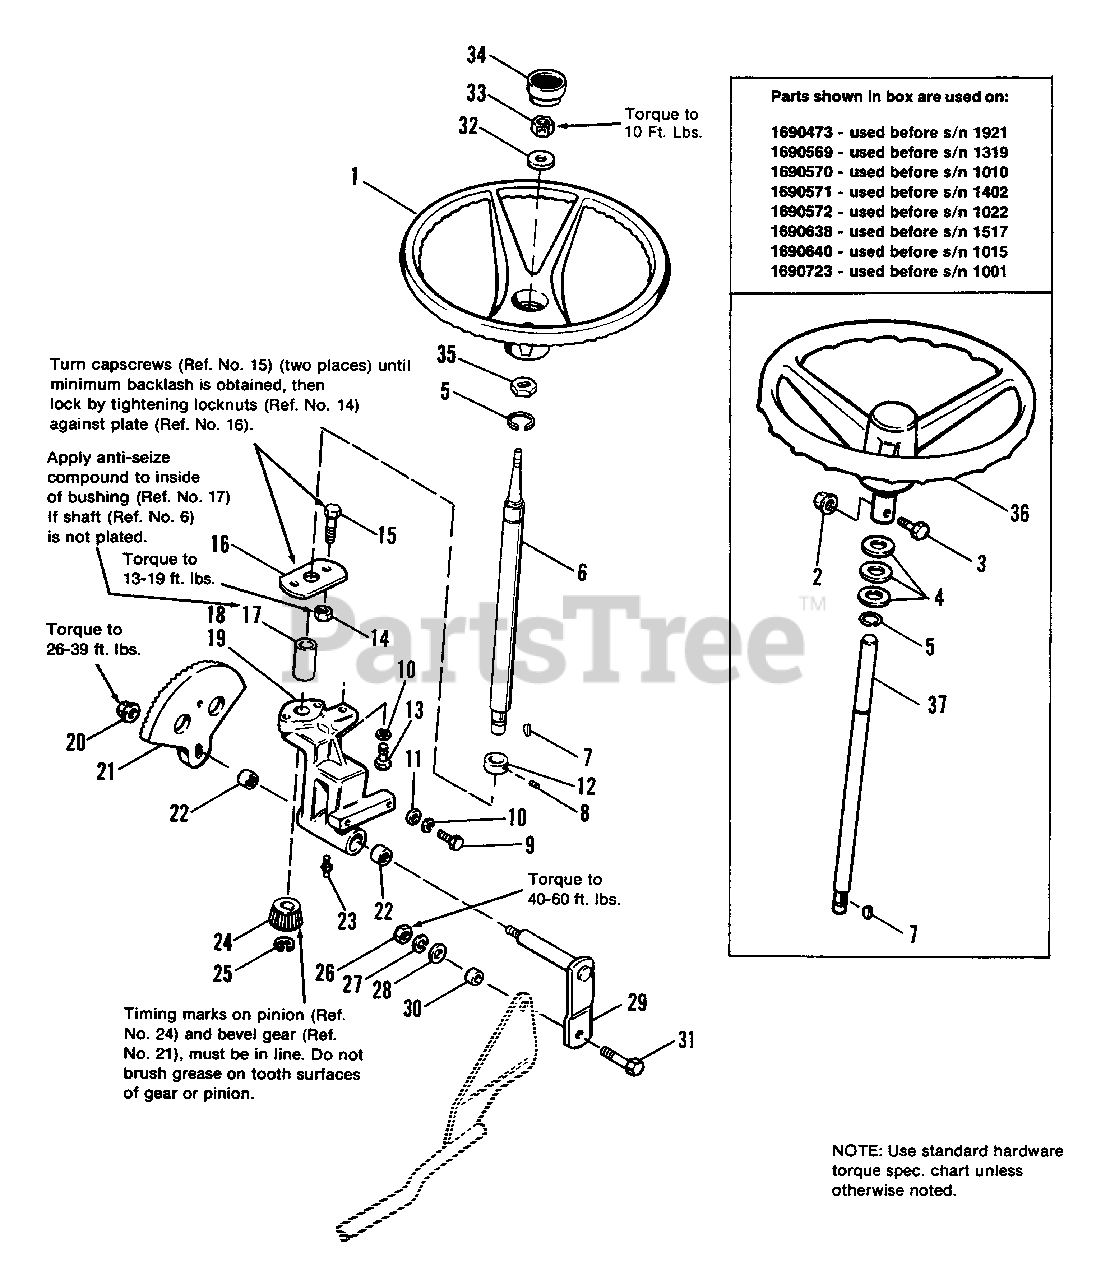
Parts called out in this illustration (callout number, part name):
1	WHEEL, Steering
2	LOCKNUT, Hex, Flange, 5/16-18
3	CAPSCREW, Hex Hd., 5/16-18 x 1-1/4
5	RING, Retaining
6	SHAFT, Steering
7	KEY, Woodruff, #6
8	SETSCREW, 5/16-18 x 1/4
9	CAPSCREW, Hex Hd., 3/8-16 x 7/8
10	LOCKWASHER, 3/8
11	WASHER, Plain, 3/8
12	COLLAR, Set
13	CAPSCREW, Hex Hd., 3/8-16 x 3/4
14	LOCKNUT, Hex, Jam, 3/8-16
15	CAPSCREW, Hex Hd., 3/8-16 x 1-1/4
16	PLATE, Steering
18	HOUSING ASSY., Steering (Incl. Ref. Nos. 17 & 22)
19	HOUSING, Steering
20	LOCKNUT, Hex, Flange, 7/16-14
21	GEAR, Bevel
22	BEARING, Needle
23	FITTING, Grease
24	PINION, Bevel
25	E-RING
26	NUT, Hex, Full, 1/2-13
27	LOCKWASHER, 1/2
28	WASHER, Plain, 1/2
29	ARM ASSY., Steering
31	CAPSCREW, Hex Hd., 1/2-13 x 1-1/2
32	WASHER, Compression
33	LOCKNUT, Hex, Cntr. 5/16-18
34	CAP, Steering Wheel
35	WASHER, Hex
36	WHEEL, Steering
37	SHAFT, Steering
